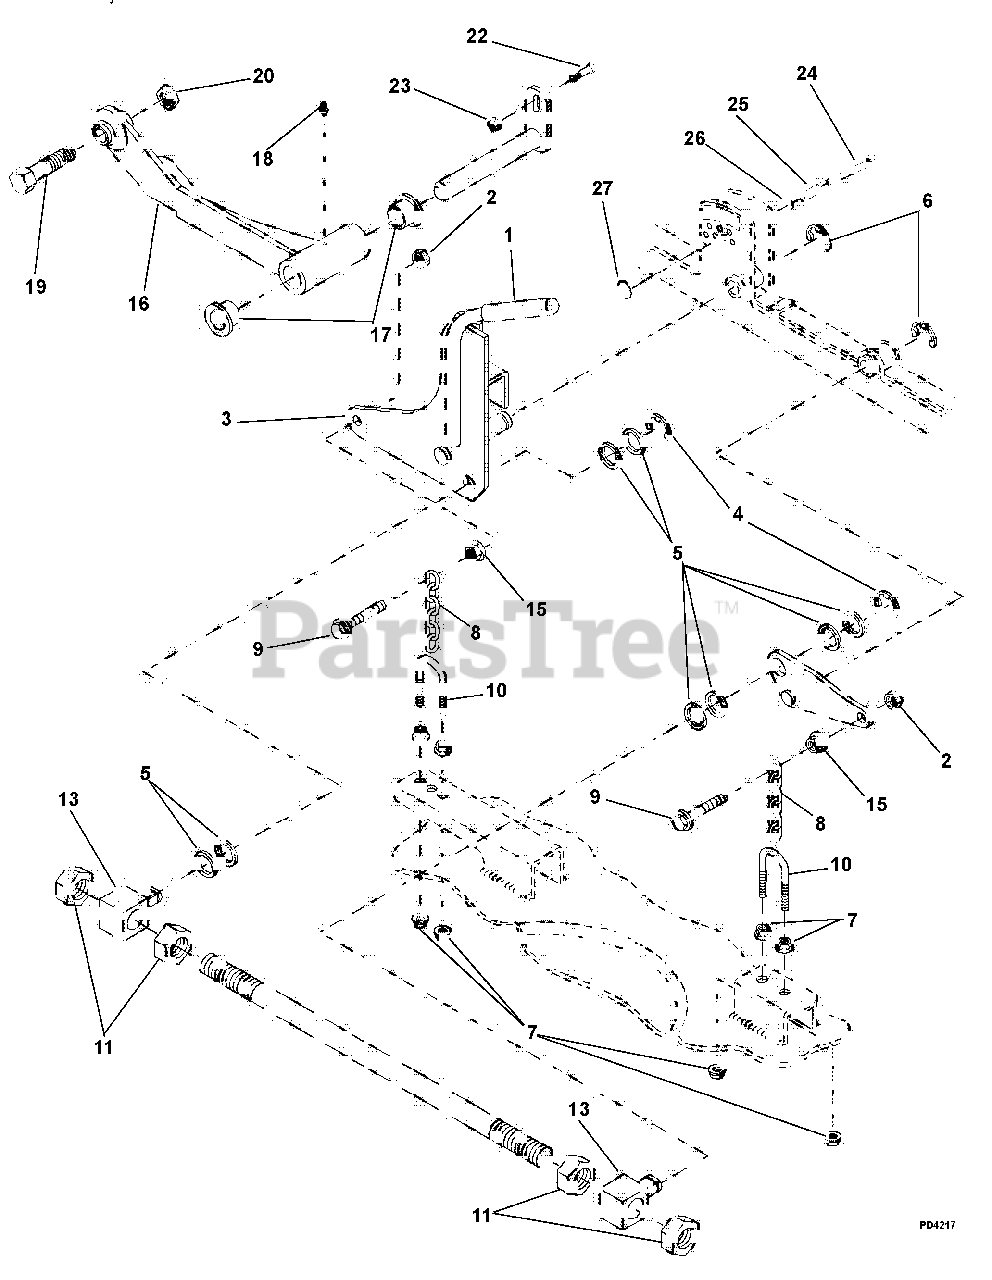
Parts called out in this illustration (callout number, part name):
1	Grip
2	Locknut, M10 x 1.50
3	Lift Arm, LH Rear
4	Snap Ring
5	Washer, JDS24 .891 x 1.375 x .048
6	Snap Ring
7	Nut, Flange .375-16
8	Chain, Deck Lift
9	Bolt, M10 x 1.5 x 40
11	Nut, Hex .75-10
12	Rod, Deck Lift
13	Swivel
14	Lift Arm, LH Front
15	Locknut, M10 x 1050
16	Thrust Arm, LH (994100)
18	Fitting, Lubrication
19	Bolt, Hex .75-10 x 3.00
20	Nut, Hex .75-10
21	Pivot Pin, Thrust Arm
22	Bolt, Round Head Square Neck .25-20 x 1.00
23	Nut, Lock, Nylon M8-1.25
24	Pin, Clevis
26	Pushnut, M12 Bolt Retainer
27	Ring, Locking
